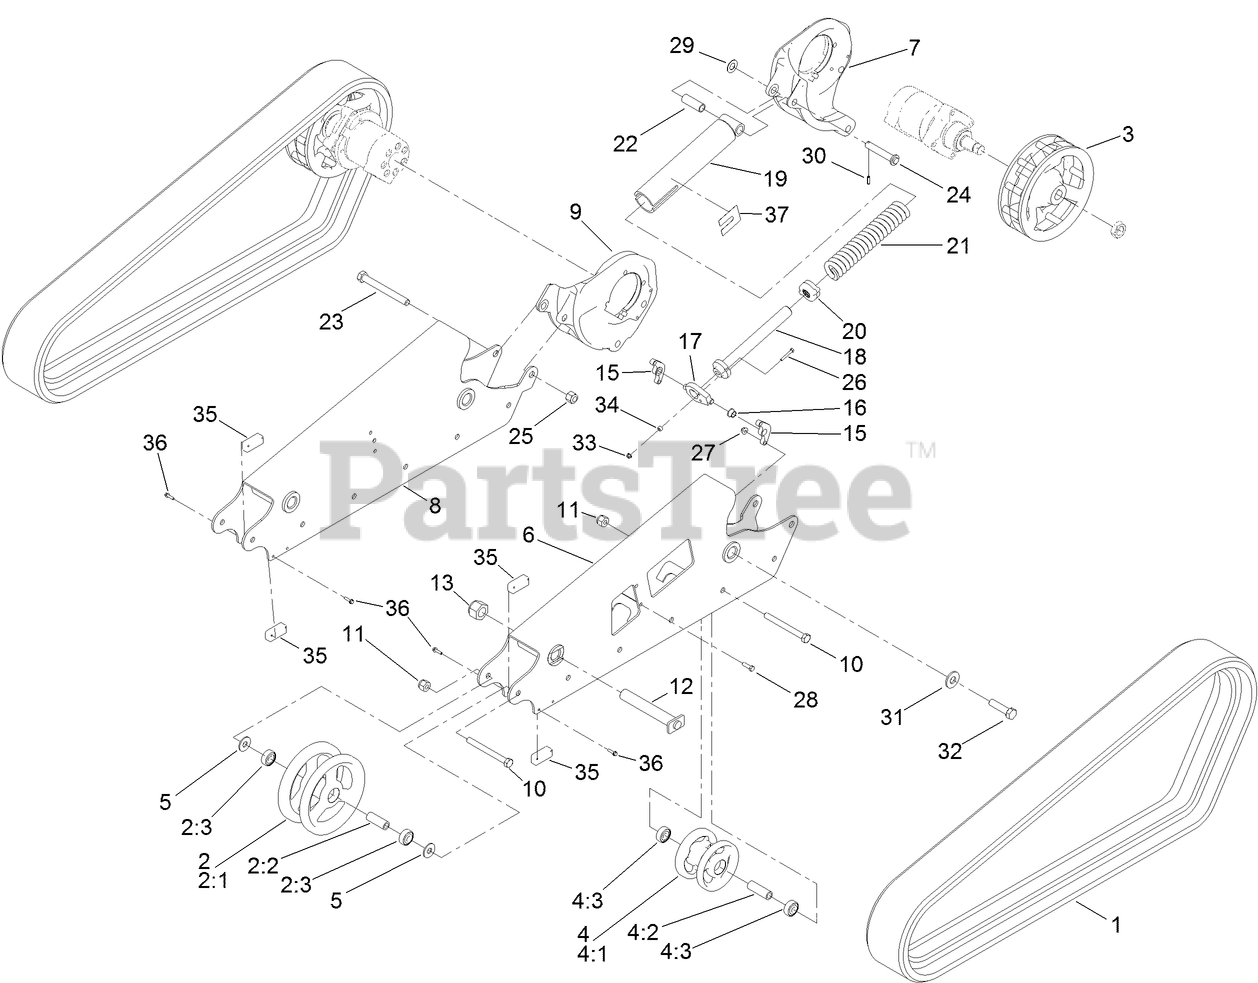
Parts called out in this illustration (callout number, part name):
1	TRACK-NARROW
2	TENSIONER WHEEL ASM
2:1	WHEEL-TENSIONER
2:2	SPACER-WHEEL, TENSIONER
2:3	BEARING-BALL
3	WHEEL-DRIVE
4	ROAD WHEEL ASM
4:1	WHEEL-ROAD
4:2	SPACER-WHEEL
4:3	BEARING-BALL
5	WASHER-FLAT
6	MOUNT-NARROW WHEEL, LH
7	MOUNT-WHEEL, LH
8	MOUNT-NARROW WHEEL, RH
9	MOUNT-WHEEL, RH
10	SCREW-HH
11	NUT-HEX
12	PIN-TRACK
13	NUT-HH
15	PLATE-MOUNT, PIVOT
16	BUSHING-BELLCRANK
17	PLATE-PIVOT
18	BOLT-TENSIONER
19	PIVOT-TENSIONER
20	BLOCK-TENSIONER
21	SPRING-COMPRESSION
22	SPACER-PIVOT
23	SCREW-HH
24	PIN-TENSIONER
25	NUT-LOCK
26	SCREW-HH
27	NUT-HF, NI
28	SCREW-HH
29	WASHER-FLAT
30	PIN-SPRING
31	WASHER
32	SCREW-HH
33	NUT-HHF
34	SPACER
35	BLOCK-TRACK
36	SCREW-HFH
37	DECAL-INDICATOR, TENSIONER
